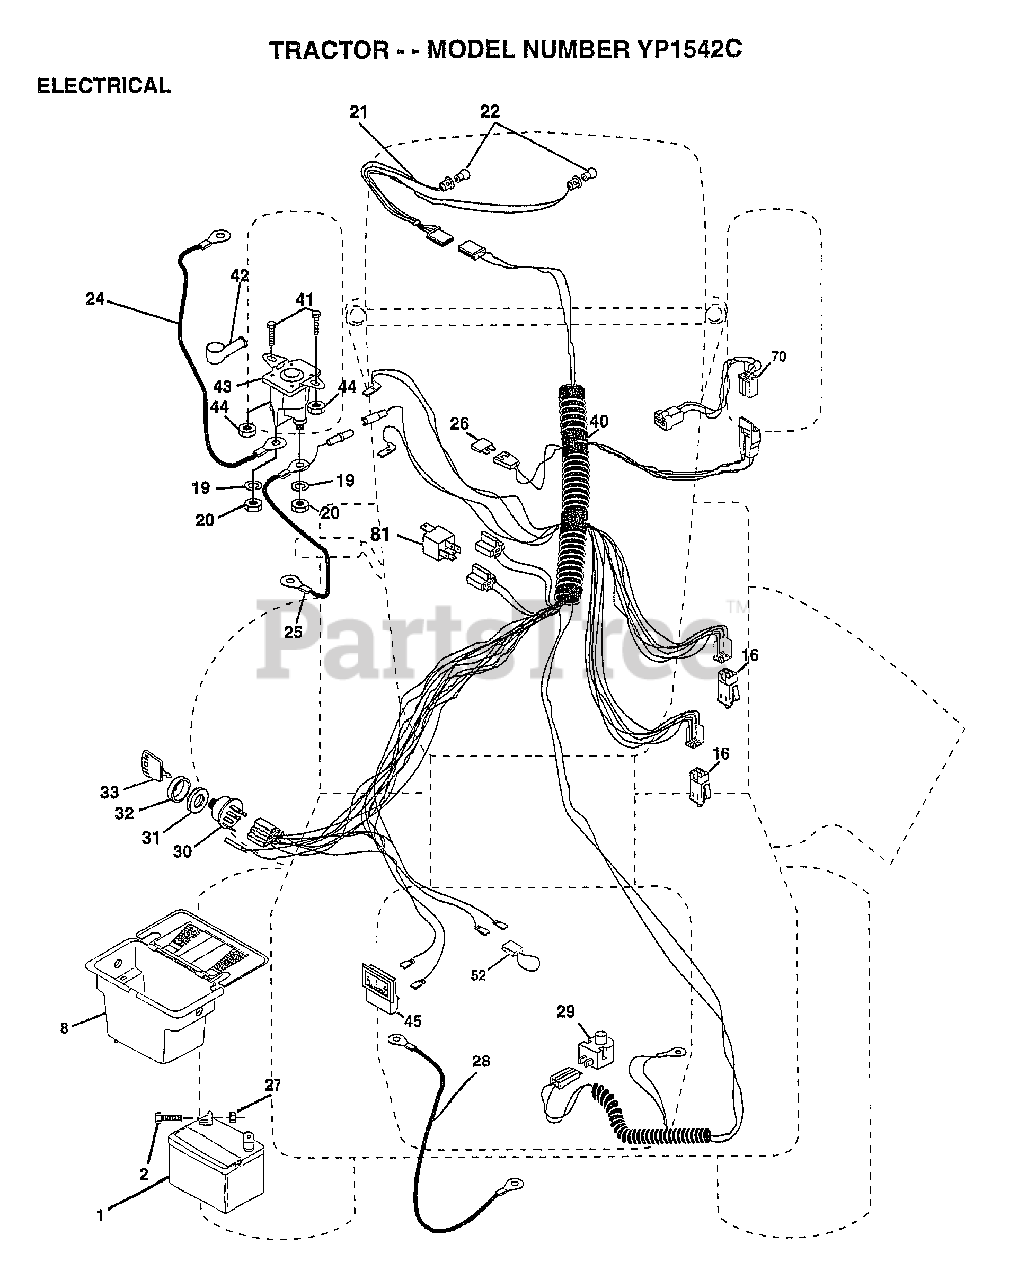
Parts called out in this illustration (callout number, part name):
2	BOLT LT
8	"CASE,BATTERY.MECH"
16	SWITCH.INTERLOCK
20	NUT
21	HARNESS.ASM.LIGHT W/4152J
22	HEADLAMP BULB
24	"CABLE T, BATTERY"
25	CABLE.BTRY.6GA.RD
26	FUSE.15 AMP
27	NUT
28	CABLE T
29	SWITCH.PLUNGER
30	SWITCH IGN 4POS
31	NUT IGNITION
32	COVER KEY SWITCH
33	KEY
40	HARNESS.IGN
41	BOLT HXHD FIN
44	NUT HXKEP 1/4X20
45	AMMETER
52	PROTECTION LOOP
70	HARNESS.ENG.TEC/KOHL
81	RELAY ASSY T
